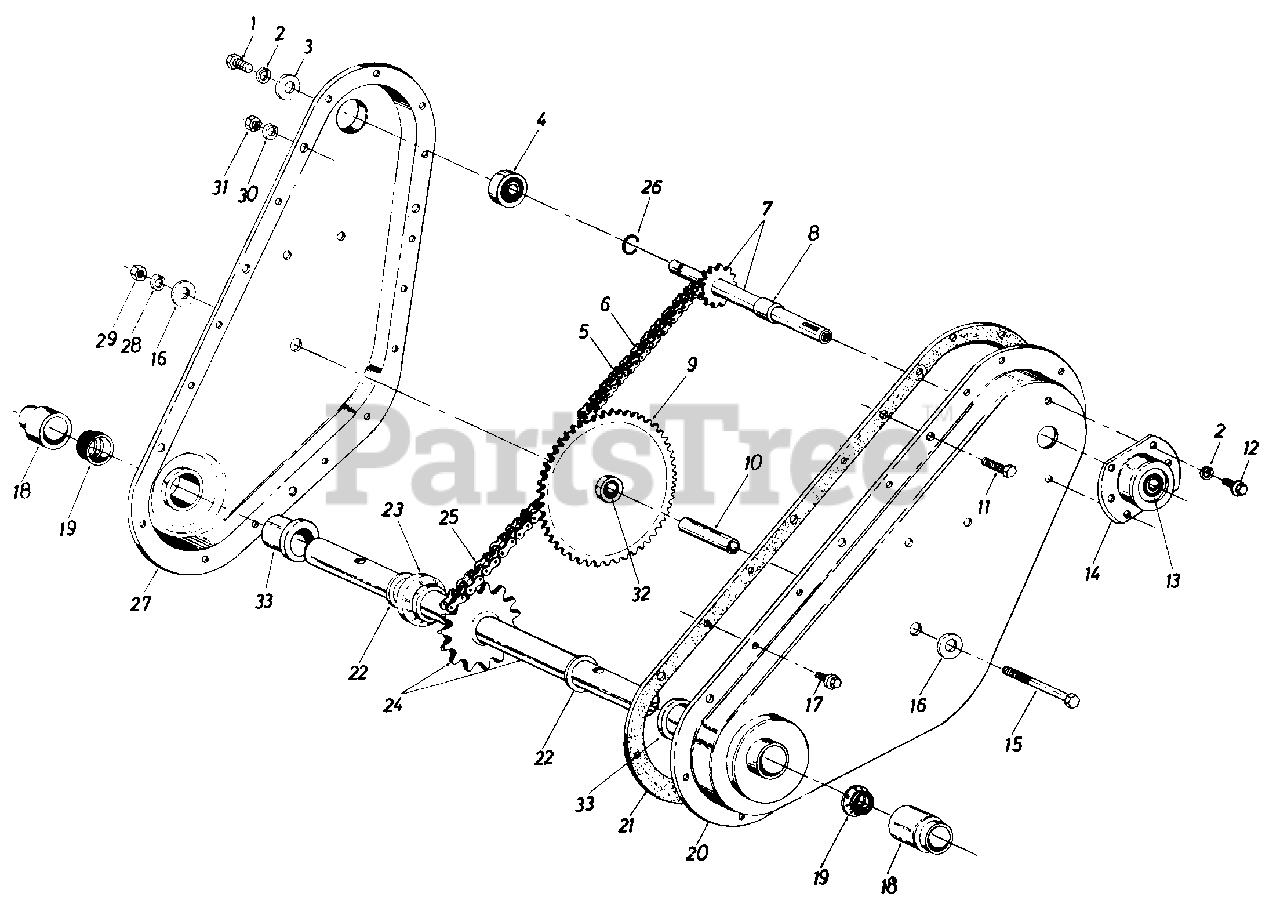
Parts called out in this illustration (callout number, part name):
1	Hex L-Scr. 1/4-28 x .625" Lg.
2	L-Wash. 1/4" l.D.
3	Fl-Wash. .25" l.D. x .93" O.D. x .125" Thk.
4	Bearing .62" l.D. x 1.38" O.D. x .437" Thk.
5	#35 Chain 3/8" Pitch x 52 Links-Endless
6	Master Link
7	Input Shaft Assembly
8	Spacer
9	Sprocket Assembly
10	Sprocket Hub Tubing 3/8" l.D. x 5/8" O.D. x 1.9" Lg.
11	Hex Scr. 5/16-18 x .625 Lg.
12	Hex Wash. Hd. Self-Tap Scr. 1/4-20 x .50" Lg.
13	Bearing .625" l.D. x 1.38" O.D. x .437" Thk.
14	Bearing Housing
15	Hex Scr. 3/8-24 x 2.75 Lg.
16	Fl-Wash. 3/8 I.D. x 1.25 0 O.D. x .100 Thk.
17	Hex Wash. Hd. Self-Tap Scr. l/4-20 x .60" Lg
18	Dust Cap
22	Thrust Wash. 1.00" l.D. x .030 Thk.
23	Step Spacer
24	Tine Shaft Assembly
25	#50 Chain 5/8" Pitch x 46 Links-Endless
26	Snap Ring
29	Hex Nut 3/8-24 Thd.
30	L-Wash. 5/16" Scr.
31	Hex Nut 5/16-18 Thd.
32	Bearing
33	Bearing
14984-0638	HOUSING ASSEMBLY RH BLACK - MTD/TROY-BILT RED (0638)
